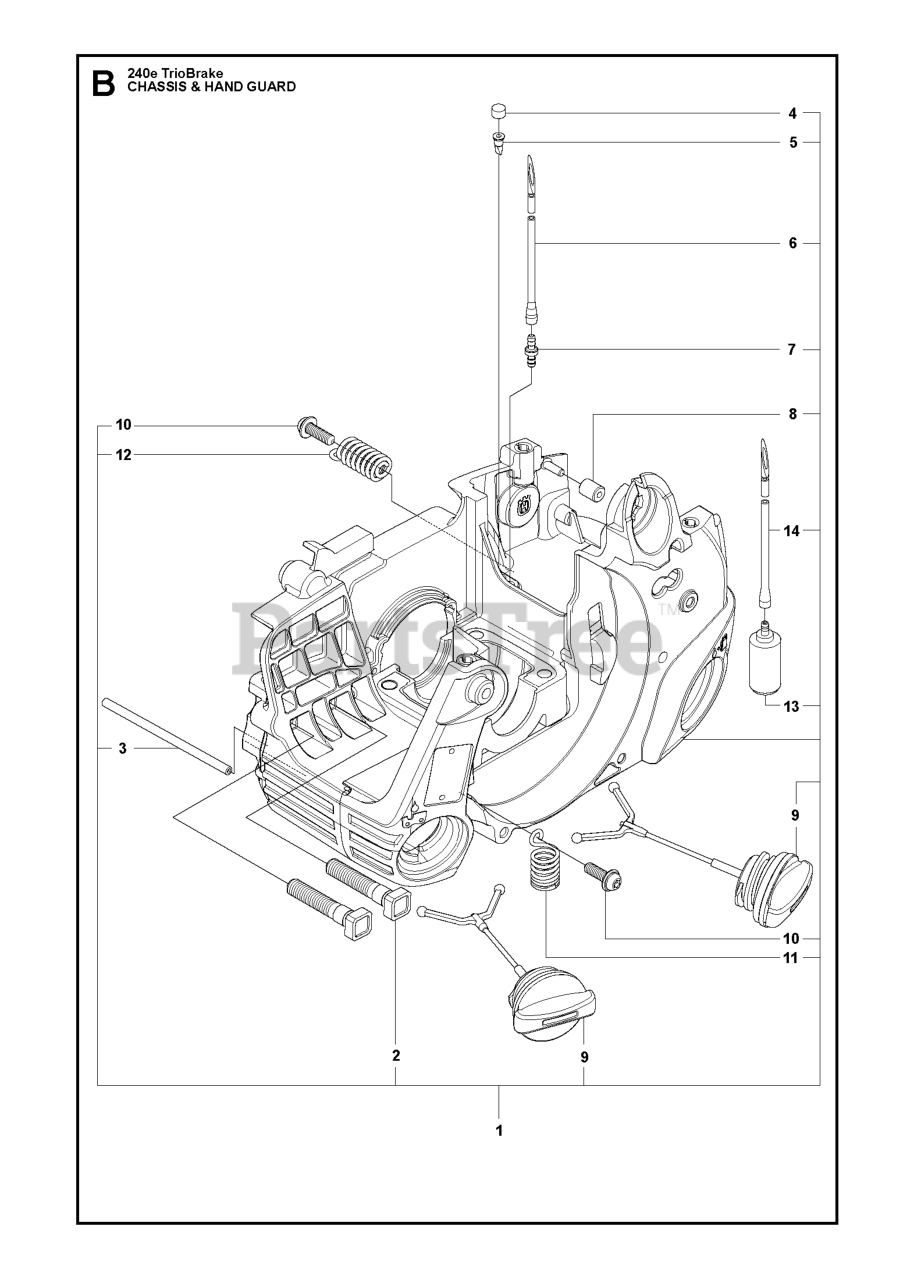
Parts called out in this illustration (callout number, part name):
1	CHASSIS ASSY
2	BOLT
4	VENT,FUEL TANK 36/41
5	VALVE-CHECK (DUCKBILL)
6	LINE KIT
7	FUEL LINE FITTING
8	ISOLATOR FILTER HOUSING
9	TANK CAP ASSY
10	SCREW,FRONT HBAR 36/41
13	ASSY FUEL PICKUP PRE FLUSHED
